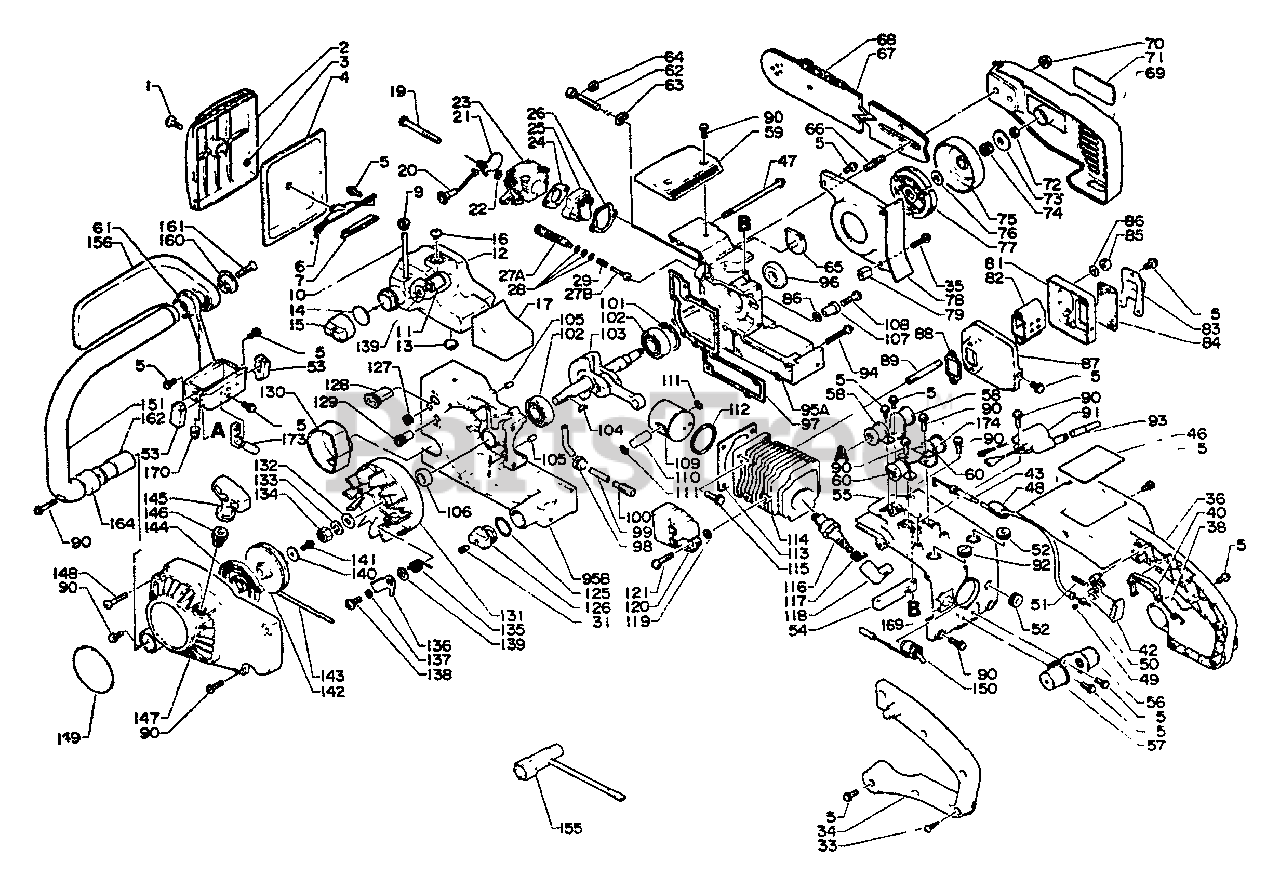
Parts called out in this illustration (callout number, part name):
1	THUMBSCREW
2	COVER, AIR FILTER
3	RING, RETAINING - 3
4	FILTER, AIR
5	SCREW - 4X10
6	BRACKET, AIR CLEANER
7	CUSHION
9	GROMMET
10	FUEL PIPE KIT
11	FILTER, FUEL
12	TANK, FUEL
14	GASKET, CAP
15	CAP
17	CUSHION
19	SCREW - 5X55
20	ROD, CHOKE
21	SHUTTER, CHOKE
22	WASHER
23	CARBURETOR C1S-K1B
24	GASKET, INTAKE
25	INSULATOR
26	GASKET, INTAKE
27	PUMP KIT
27A	PUMP KIT
27B	PUMP KIT
28	O-RING - 5
31	VENT, TANK
33	SCREW - 4X16 -- TAPPING
34	HANDLE - REAR
35	SCREW - 4X20
36	HANDLE - REAR
38	SPRING, LOCKOUT LEVER
40	LOCKOUT, THROTTLE
42	TRIGGER, THROTTLE
43	CABLE, THROTTLE
46	LABEL
48	GROMMET
49	SCREW - SET
51	SPRING, TRIGGER
54	SPACER
55	COVER, CYLINDER
56	CUSHION
57	CUSHION
59	COVER, INTAKE
60	Cushion (U)
61	BRACKET, HANDLE - UPPER
62	SCREW, TENSIONER
63	TENSIONER, CHAIN
65	PLUG
66	STUD, GUIDE BAR
67	GUIDE BAR - 14" (35cm)
68	SAW CHAIN - 91SG-52E
69	GUARD, SPROCKET
70	NUT - 6 -- FLANGE
71	LABEL - ECHO
72	LOCKNUT - 6
74	BEARING, NEEDLE
75	DRUM, CLUTCH
76	WASHER, CLUTCH
77	CLUTCH ASSY
78	PLATE, SEAL
79	SPACER
81	LID, MUFFLER
82	BAFFLE, MUFFLER
83	GUIDE, EXHAUST
84	SCREEN, SPARK ARRESTOR
85	LOCKNUT - 5
86	WASHER - 5
87	GUIDE, EXHAUST
88	GASKET, EXHAUST
90	SCREW - 4X16
91	COIL, IGNITION
93	TUBE
94	SCREW - 4X30
95	CRANKCASE
95A	CRANKCASE
95B	CRANKCASE
96	SEAL, OIL
97	GASKET, CRANKCASE
98	GROMMET
99	PIPE - OIL
100	FILTER, OIL
101	RING, RETAINING - 32
102	BEARING, BALL - 6201
103	CRANKSHAFT ASSY
105	PIN - LOCATING
106	SEAL, OIL
107	CATCHER, CHAIN
108	SCREW - 5X20
109	PISTON
110	PIN, PISTON
111	RING, RETAINING
112	RING, RETAINING
113	GASKET, CYLINDER
114	CYLINDER
115	SCREW - 5X20
116	SPARK PLUG -- CJ-8Y
117	TERMINAL, SPARK PLUG CAP
118	CAP, SPARK PLUG
119	SPACER
120	COIL, IGNITION
121	SCREW - 5X22
125	O-RING - 16
126	CAP, OIL TANK
128	GROMMET
129	GROMMET
130	SEAL
131	FLYWHEEL
132	WASHER - 8
133	LOCKWASHER - 8
135	SPRING, RETURN
136	PAWL, STARTER
138	SCREW
139	WASHER - 5
141	SCREW - 4X10
142	REEL, ROPE
143	ROPE, STARTER - 3X850
144	SPRING, REWIND
145	GRIP, STARTER
146	GUIDE, ROPE
147	CASE, STARTER
148	SCREW - 4X25
149	LABEL - ECHO
150	SWITCH, IGNITION
151	HANDLE - FRONT
155	T-WRENCH - 10X19mm
156	GUARD
160	Holder, guard
161	SCREW - 5X25
162	CUSHION
169	LABEL - SWITCH
170	CUSHION
